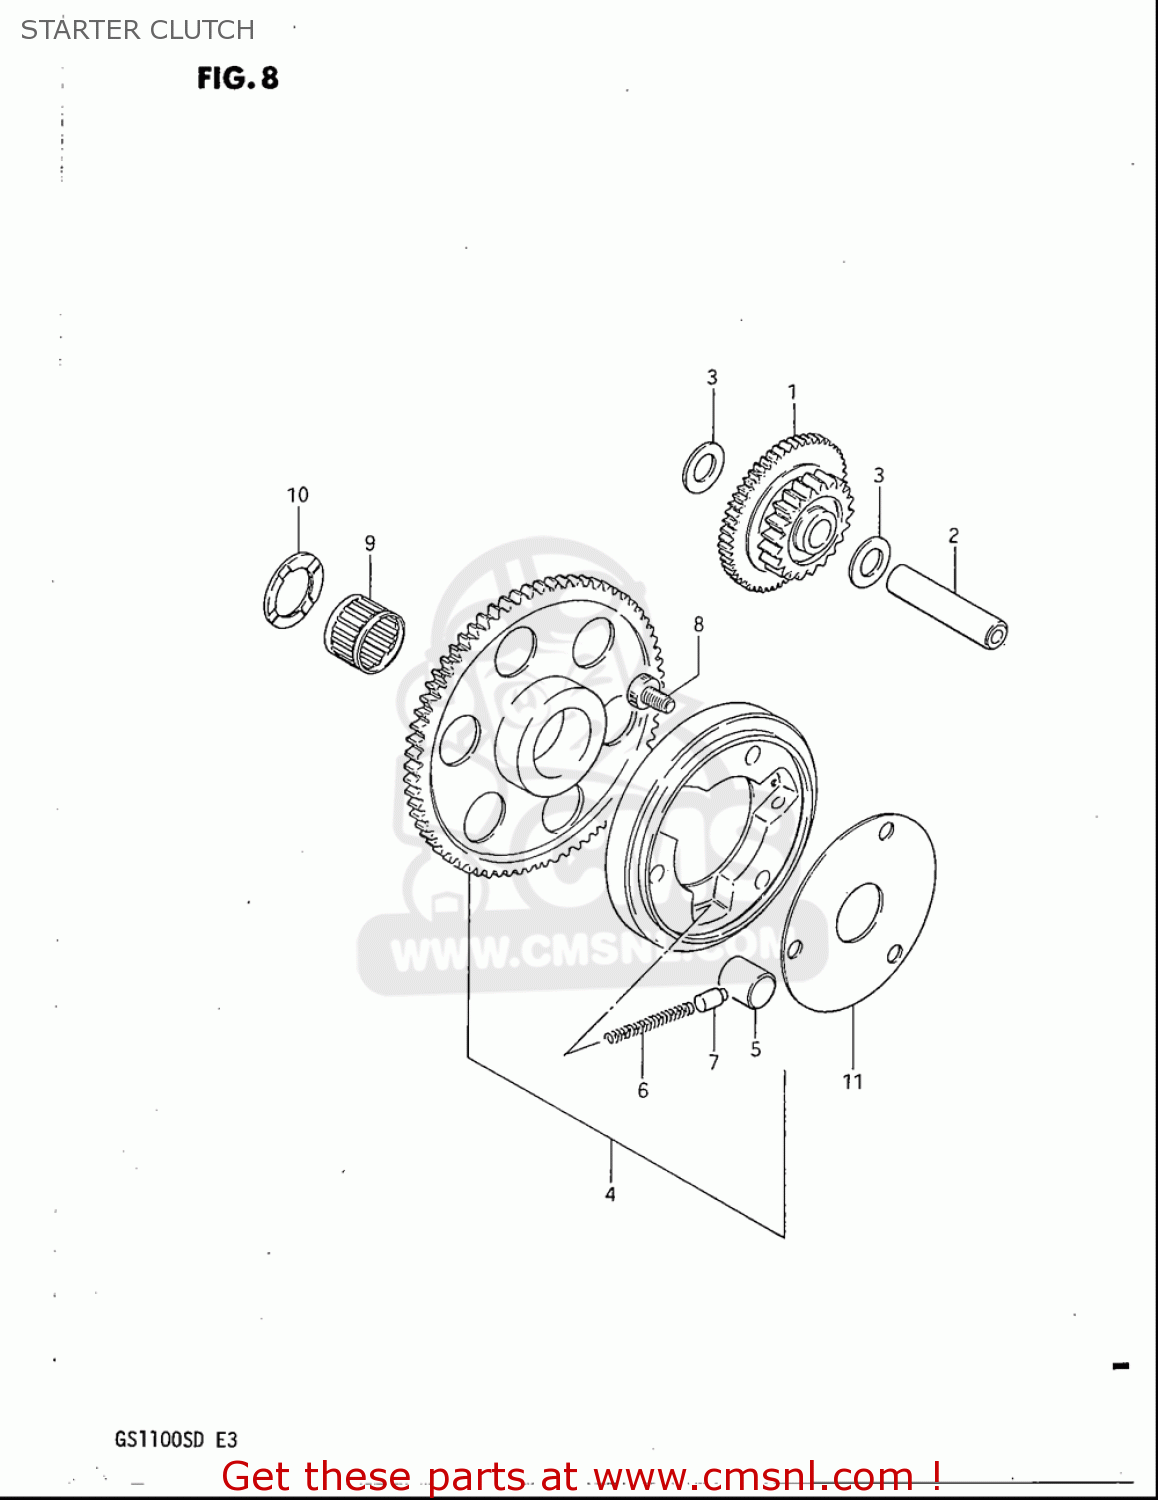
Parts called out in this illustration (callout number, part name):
1	GEAR,STARTER IDLE
2	PIN(7.4X13X56)
3	WASHER(13.3X25X0.85)
4	CLUTCH SET,STARTER
5	ROLLER(15X13)
6	SPRING
7	PIECE,PUSH
8	BOLT
9	BEARING(25X31X20)
10	WASHER(25X38X2.5)
